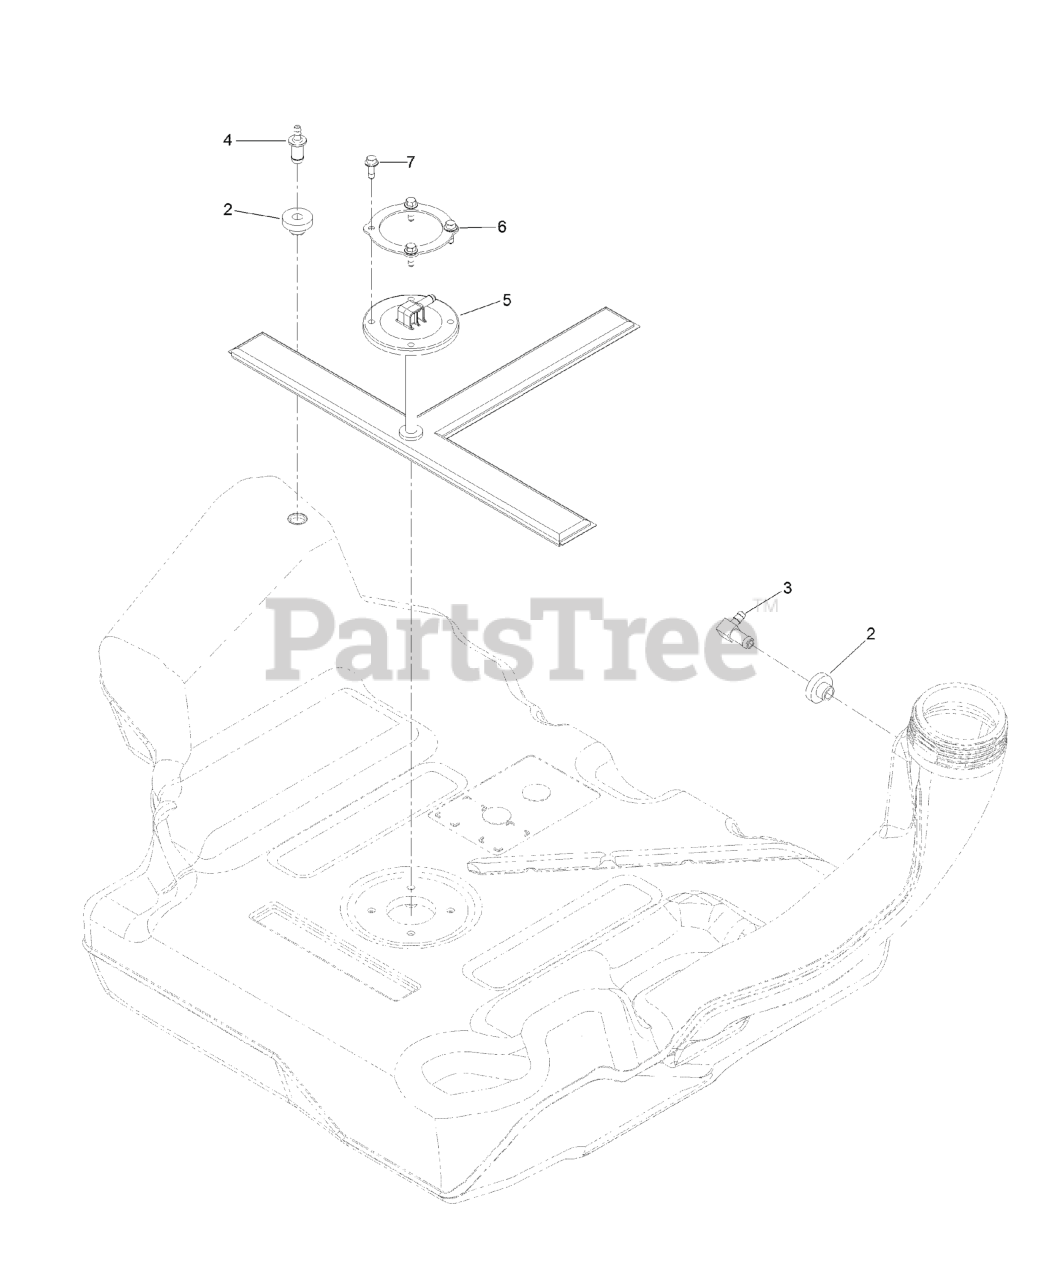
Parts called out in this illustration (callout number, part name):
2	BUSHING
3	FITTING-90 DEG
4	FITTING-ORIFICE, STRAIGHT
5	PICKUP-FUEL
6	RING-RETAINER
